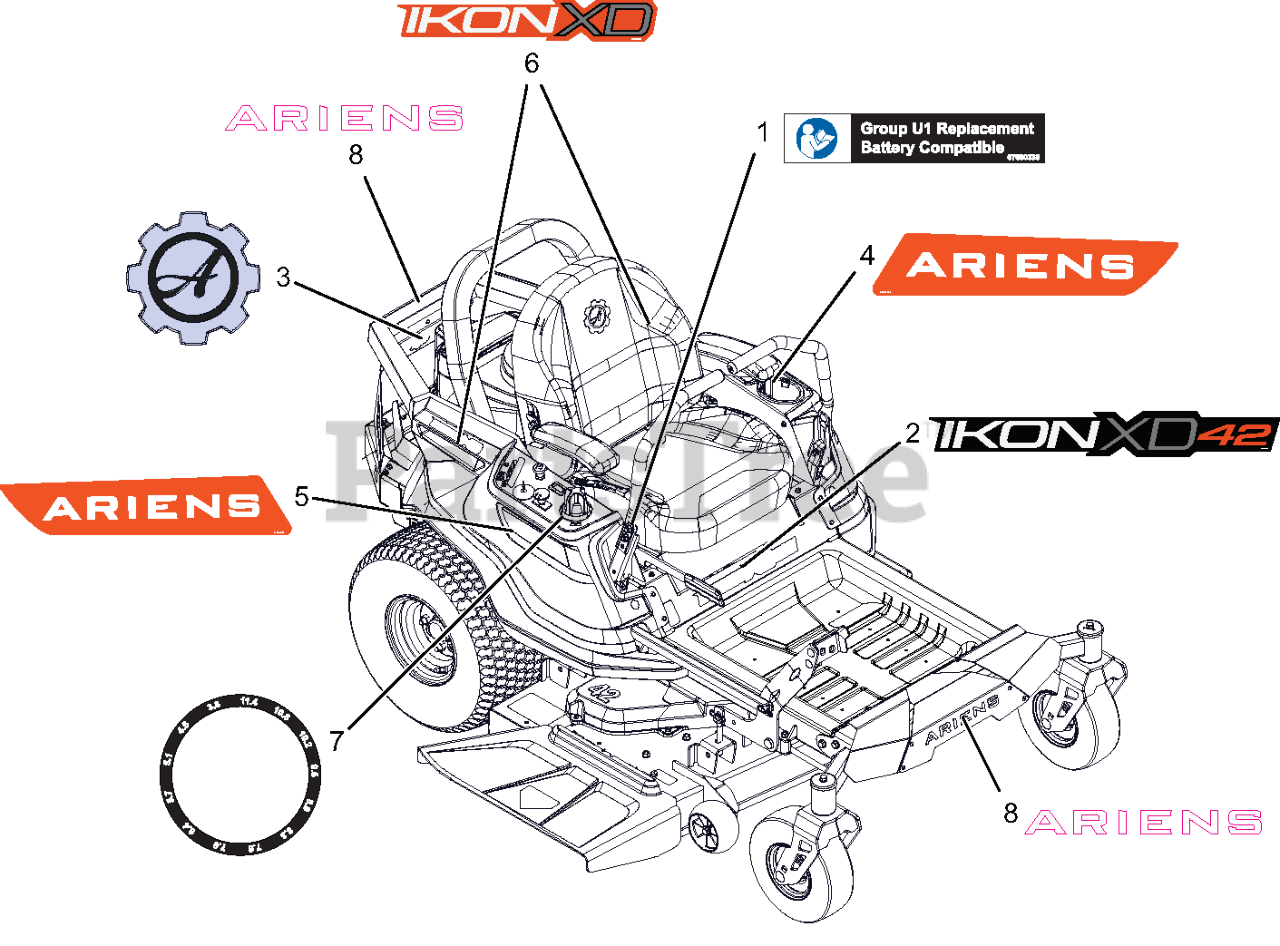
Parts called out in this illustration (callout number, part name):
1	DECAL, U1 BATTERY REPLACEMENT
2	DECAL, IKON-XD 42"
3	DECAL, ARIENS-GEAR BADGE -THK
4	DECAL, FENDER LH
5	DECAL, FENDER RH
6	DECAL, IKON-XD
7	DECAL, CUT HEIGHT - IKON CE
8	DECAL - ARIENS 9.625"
